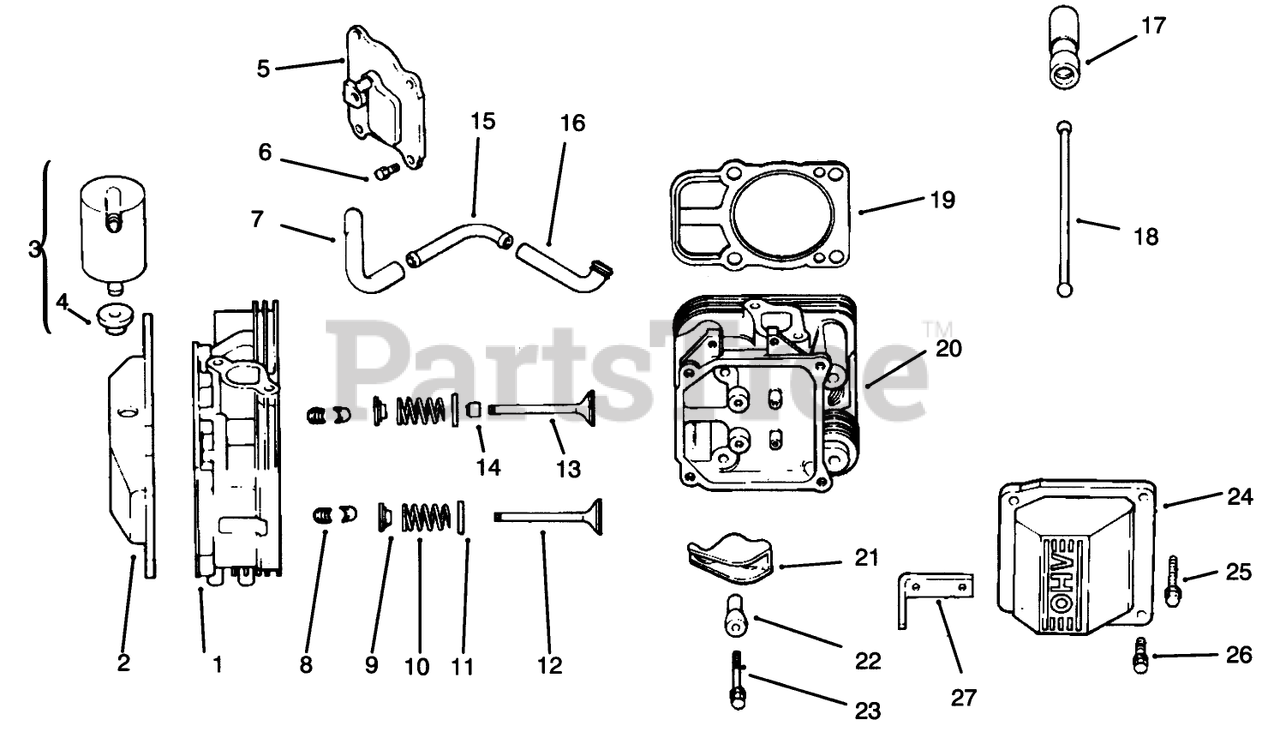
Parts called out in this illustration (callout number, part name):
1	Head ASM-#1 Cylinder (Only On: 72103, 72083)
2	Cover-Rocker (Only On: 72103)
3	Kit-Breather INCL 4 (Only On: 72103)
4	Grommet-Rubber (Only On: 72103)
5	Cover-Breather (Only On: 72103)
7	Hose-Breather (Only On: 72103)
8	Kit-Retainer
9	Cap-Valve Spring
10	Spring-Valve
11	Retainer-Spring
12	Valve-Exhaust
13	Valve-Intake
14	Seal-Valve Stem
15	Fitting (Only On: 72103)
16	Hose-Breather (Only On: 72103)
17	Lifter-Valve
18	Rod-Push (Only On: 72103,72083)
19	Gasket-Cylinder Head
20	Head ASM-#2 Cylinder (Only On: 72103, 72083)
21	Arm-Rocker (Only On: 72103,72083)
22	Ball-Rocker Pivot
24	Cover-Rocker (Only On: 72103)
25	Screw
27	Strap-Lifting
